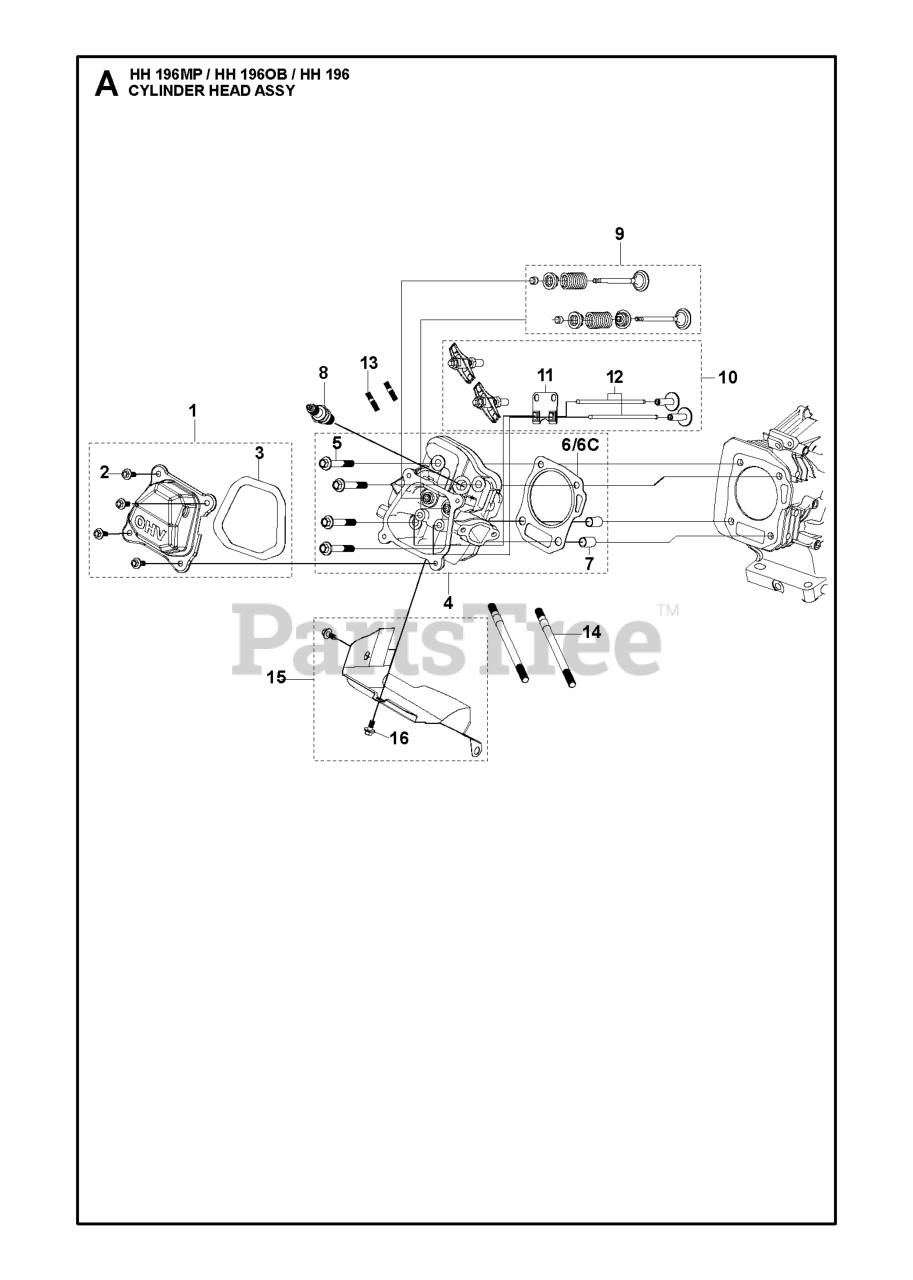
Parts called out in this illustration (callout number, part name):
5	Husqvarna TBD
7	PIN LOCATION PIN
8	SPARK PLUG HQT-7 RESISTOR
